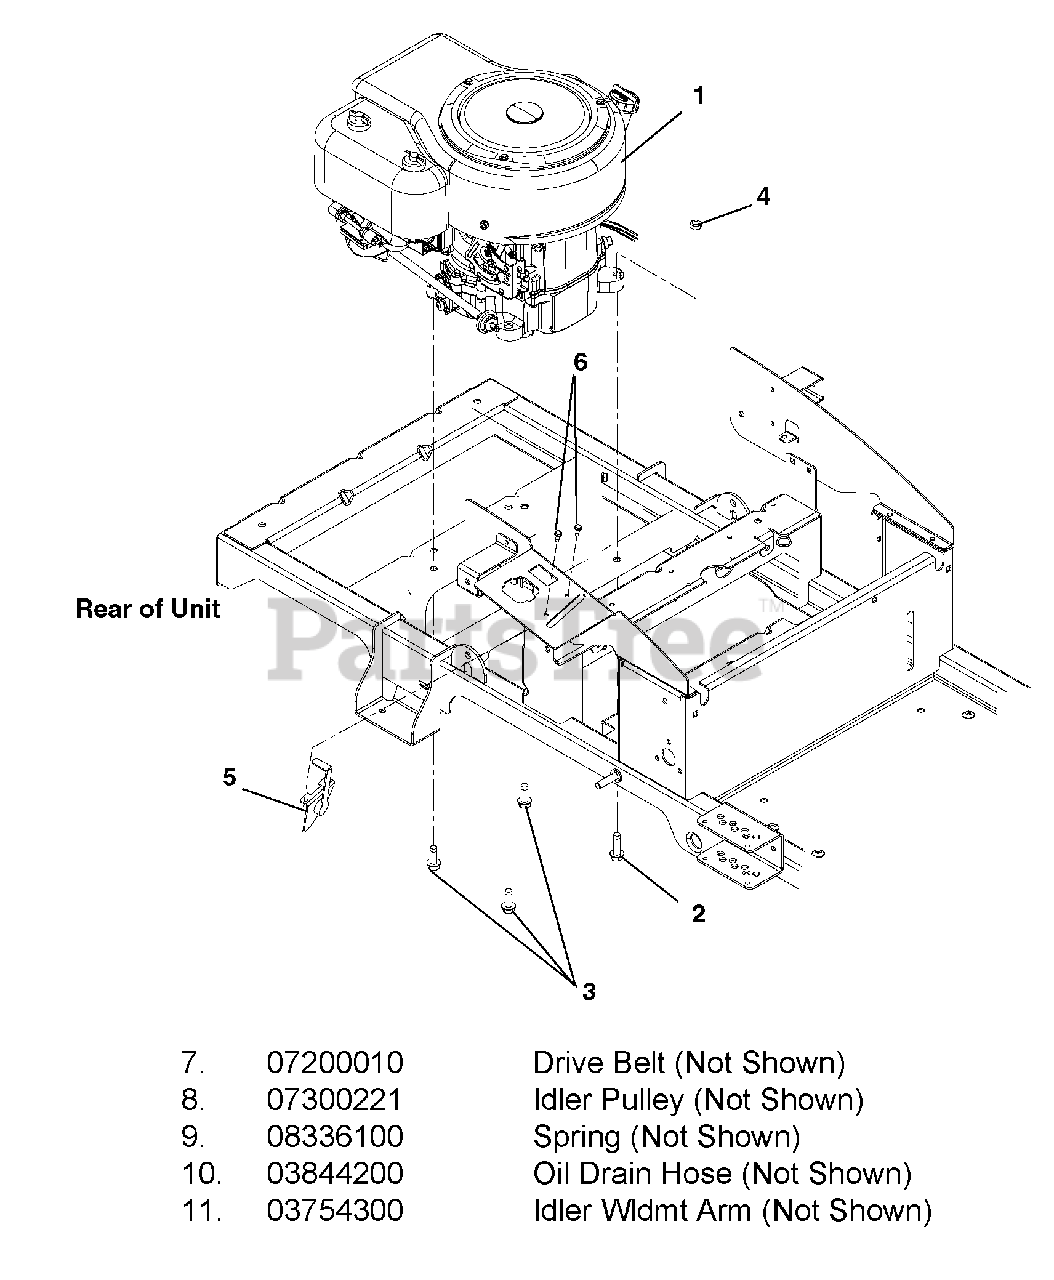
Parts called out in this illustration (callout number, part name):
1	Engine, 13.5 HP Briggs and Stratton IC
2	Screw, Tapping .38-16 x 1.25 Hex Washer Head
3	Screw, Tapping .38-16 x 1.00 Hex Washer Head
4	Nut, Locking Jam .375-16
5	Throttle/Choke Cable
6	Screw, Tapping 10-24 x .50 Hex Washer Head
